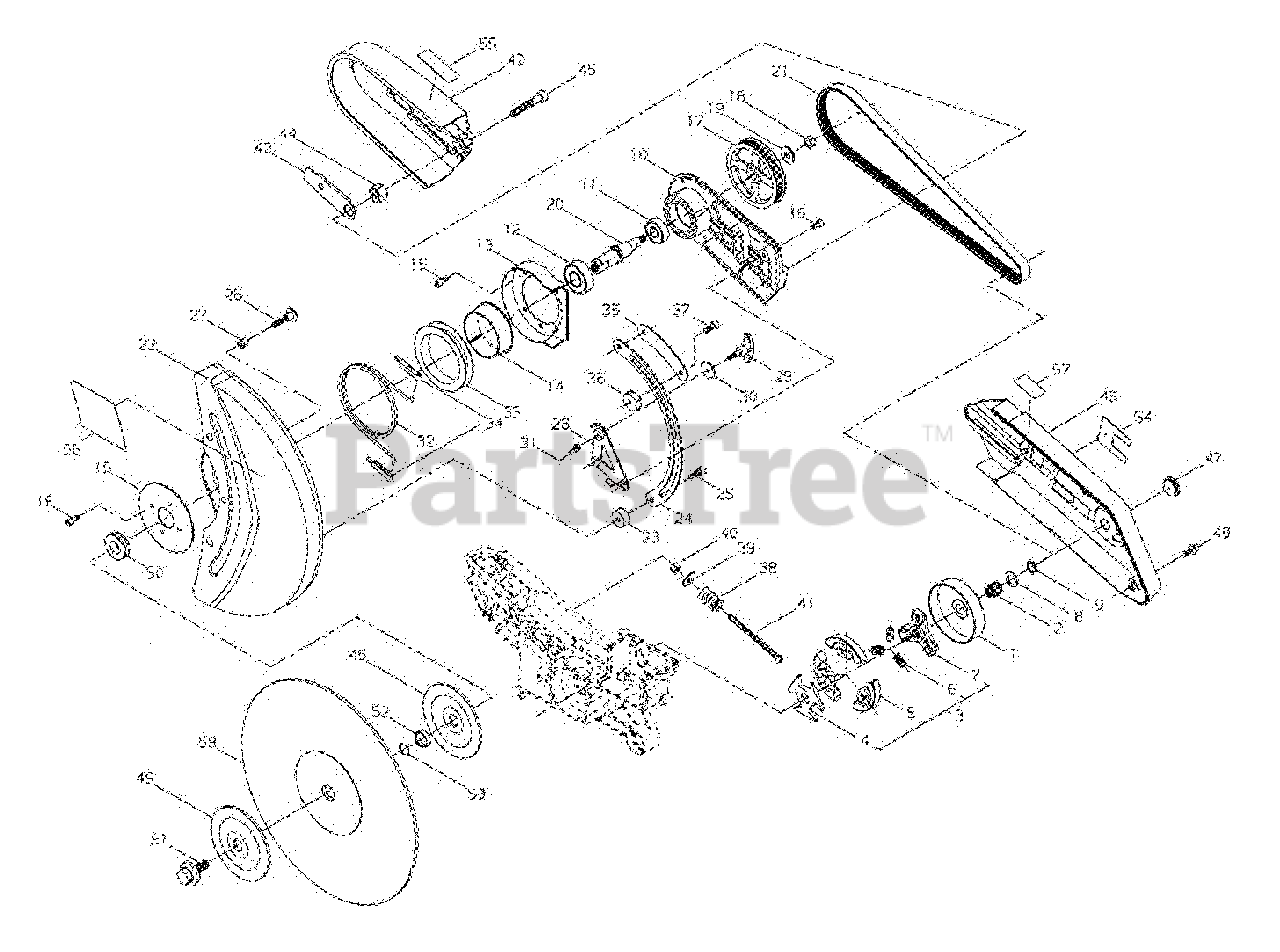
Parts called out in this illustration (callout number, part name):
1	DRUM, CLUTCH
2	BEARING, NEEDLE
3	CLUTCH ASSY
4	BOSS, CLUTCH B
5	SHOE, CLUTCH
6	SPRING, CLUTCH
7	BOSS, CLUTCH A
8	THRUST PLATE
9	RING, SNAP
10	BEARING CASE
11	BEARING, BALL 6201
12	BEARING, BALL 6203
13	PLATE, SPRING
14	RING
15	BEARING PLATE
16	BOLT 5×16
17	PULLEY, DRIVE
18	NUT M8
19	COLLAR
20	DRIVESHAFT
21	DRIVE BELT
22	GUARD, WHEEL
23	COLLAR
24	SLIDE PLATE
25	BOLT 6×20
26	BOLT, CLUTCH
28	PLATE, LOCK
29	KNOB
30	WASHER Ø23ר6.5×2 MM
31	NUT
32	SPRING
33	GUIDE, SPRING
34	SPRING HOLDER
35	PLATE, ANGLE
36	NUT
37	BOLT
38	SPRING
39	WASHER
40	NUT
41	SCREW
42	PULLEY COVER
43	TENSION PLATE
44	TENSION BLOCK
45	BOLT
46	COVER, CLUTCH
47	PLUG
48	BOLT, ADHESIVE M5×14
49	FLANGE
50	COLLAR
51	BOLT - FLANGE
52	COLLAR
53	RING, RETAINING
54	LABEL - TRADE
55	LABEL - INSTRUCTION
56	LABEL - CAUTION
57	LABEL -ARROW
58	CUT OFF WHEEL
